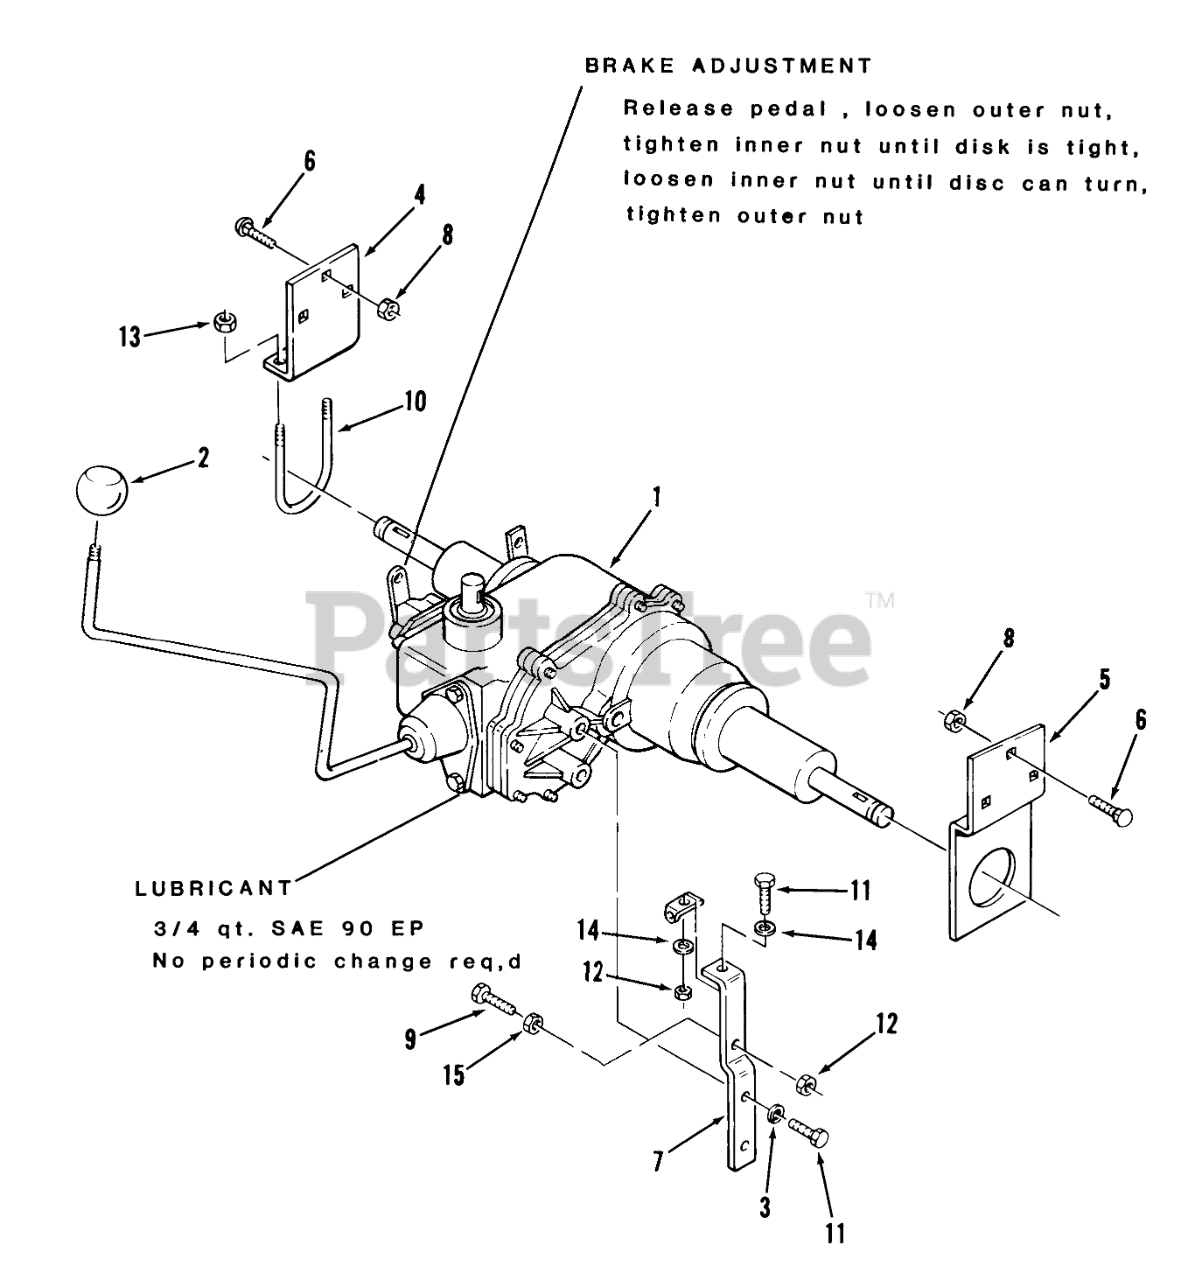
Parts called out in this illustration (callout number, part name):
1	Transmission-Peerless Mod. 601-001
3	Lockwasher
4	BRACKET-AXLE RH
5	BRACKET-AXLE LH
6	CARRIAGE BOLT -4
7	Bracket Trans. Mounting
8	Nut
9	Bolt 5/16-18 x 2
10	"U" Bolt Axle Mount
11	Bolt
12	Nut
13	Nut
14	WASHER 5/16 SAE
15	Jam Nut 5/16-18
